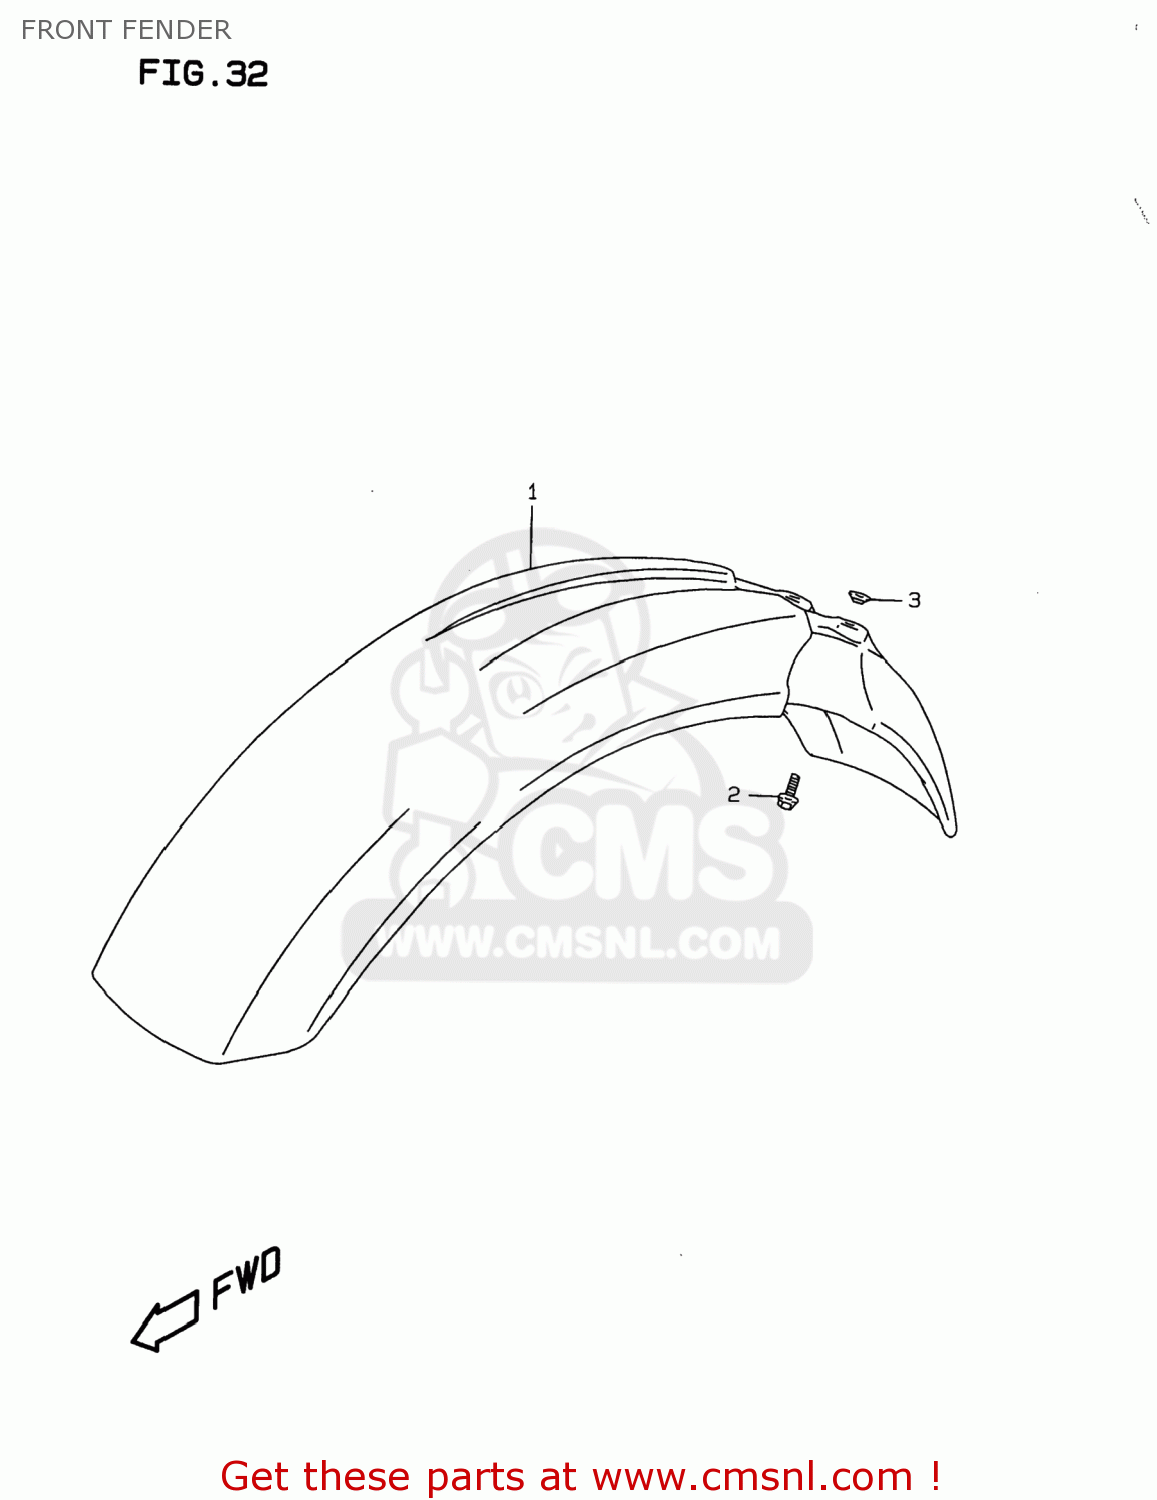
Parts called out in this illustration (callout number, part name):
1	FENDER,FR
2	BOLT(6X16)
3	WASHER
